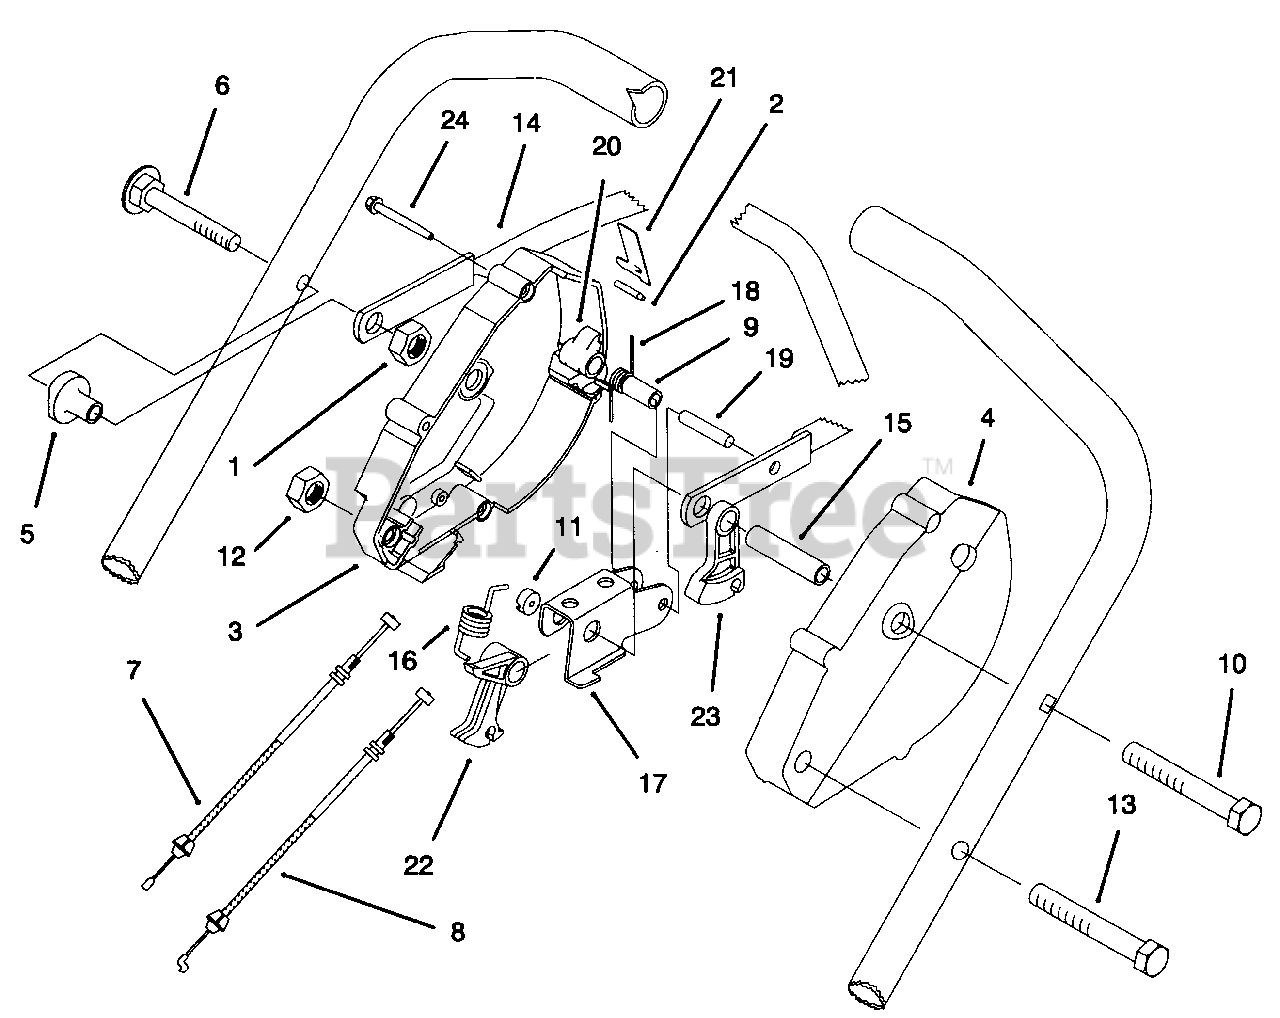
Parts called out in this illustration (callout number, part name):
1	Nut-Flange Nylon
2	Pin-Insert
3	Housing-Control R.H.
4	Housing-Control L.H.
5	Spacer-Support
7	Cable-BBC
8	Cable-Traction
9	Bushing-PM
10	Screw-Handle
11	Washer-Nylon
12	Nut-Lock
13	Screw Handle
14	Bar-Control
16	Spring-Detent
18	Spring-Torsion
19	Pin-Roll
20	Hook-Control
21	Spring-Leaf
22	Lever-Cable
23	Lever-Traction
24	Screw-Hex Washer Hd.
